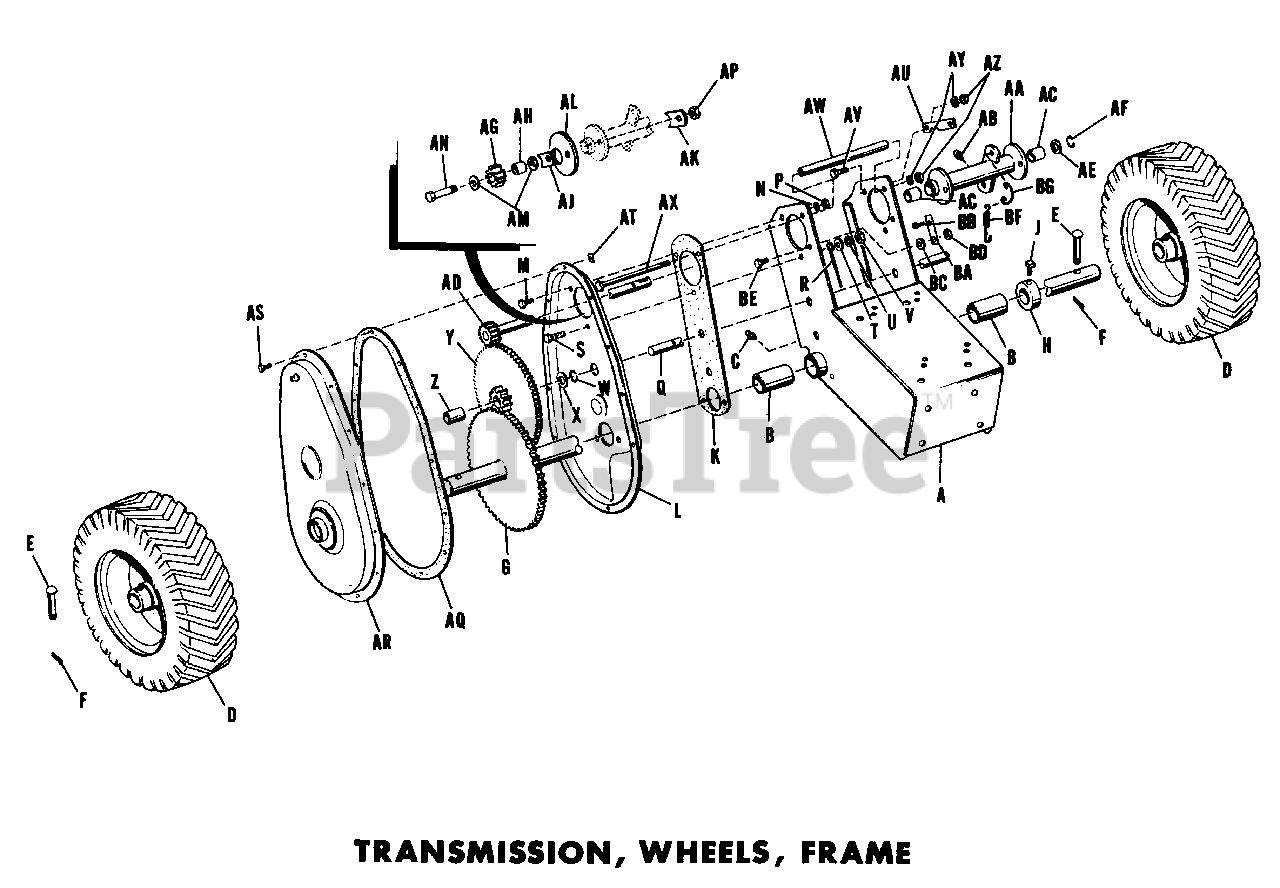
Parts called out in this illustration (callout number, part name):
A	Frame Assembly
B	Bearing, Axle
C	Fitting, Grease
D	Wheel & Tire Assembly
E	Pins
F	Pin, Cotter, 1/8" x 1" lg.
G	Axle & Gear Assembly
H	Collar, Set
J	Screw, Set, Square Hd., 5/16"-18 NC x 1/2"
K	Gasket, Bearing Housing
L	Gear Case
M	Capscrew, Hex, 5/16"-18 NC x 5/8 lg.
N	Washer, Lock, 5/16"
P	Nut, Hex, Full, 5/16"-18 NC
Q	Shaft, intermediate
R	Pin, Lock
S	Capscrew, Hex. , 3/8"-16 NC x 1" lg.
T	Washer, Plain, 3/8"
U	Washer, Lock, 3/8"
V	Nut, Hex, Full, 3/8"-16 NC
W	Ring, Retaining
Y	Gear Assembly, Intermediate
Z	Bearing, Intermediate Pinion
AA	Housing Assembly, Bearing
AB	Fitting, Grease
AD	Shaft Assembly, Pulley
AF	Ring, Retaining
AG	Pinion, Reverse
AH	Spacer, Pinion
AJ	Spacer, Reverse Pinion
AK	Plate, Lock
AM	Washer, Plain, 5/16"
AN	Bolt, Hex Head, L.H.
AP	Nut, Hex, Full, L.H.
AQ	Gasket, Gear Case
AR	Cover Assembly, Gear Case
AS	Screw, Self Tapping, #10 x 3/8" lg.
AT	Nut, Speed
AU	Plate, Friction Stop
AV	Screw, Cap, Hex. , 5/16"-18 NC x 3/4" lg.
AW	Spacer, Frame
AX	Bolt, Frame
AY	Washer, Lock, 5/16"
AZ	Nut, Hex, Full, 5/16"-18 NC
BA	Detent, Neutral
BB	Screw, Self Tapping, #10 x 3/8" lg. Round Head
BC	Washer, Plain, 1/4"
BD	Nut, Hex, Full, 1/4"-20 NC
BE	Capscrew, Hex, 1/4"-20 NC x 5/8" lg.
BF	Spring, Reverse Lever
BG	Extension, Spring
